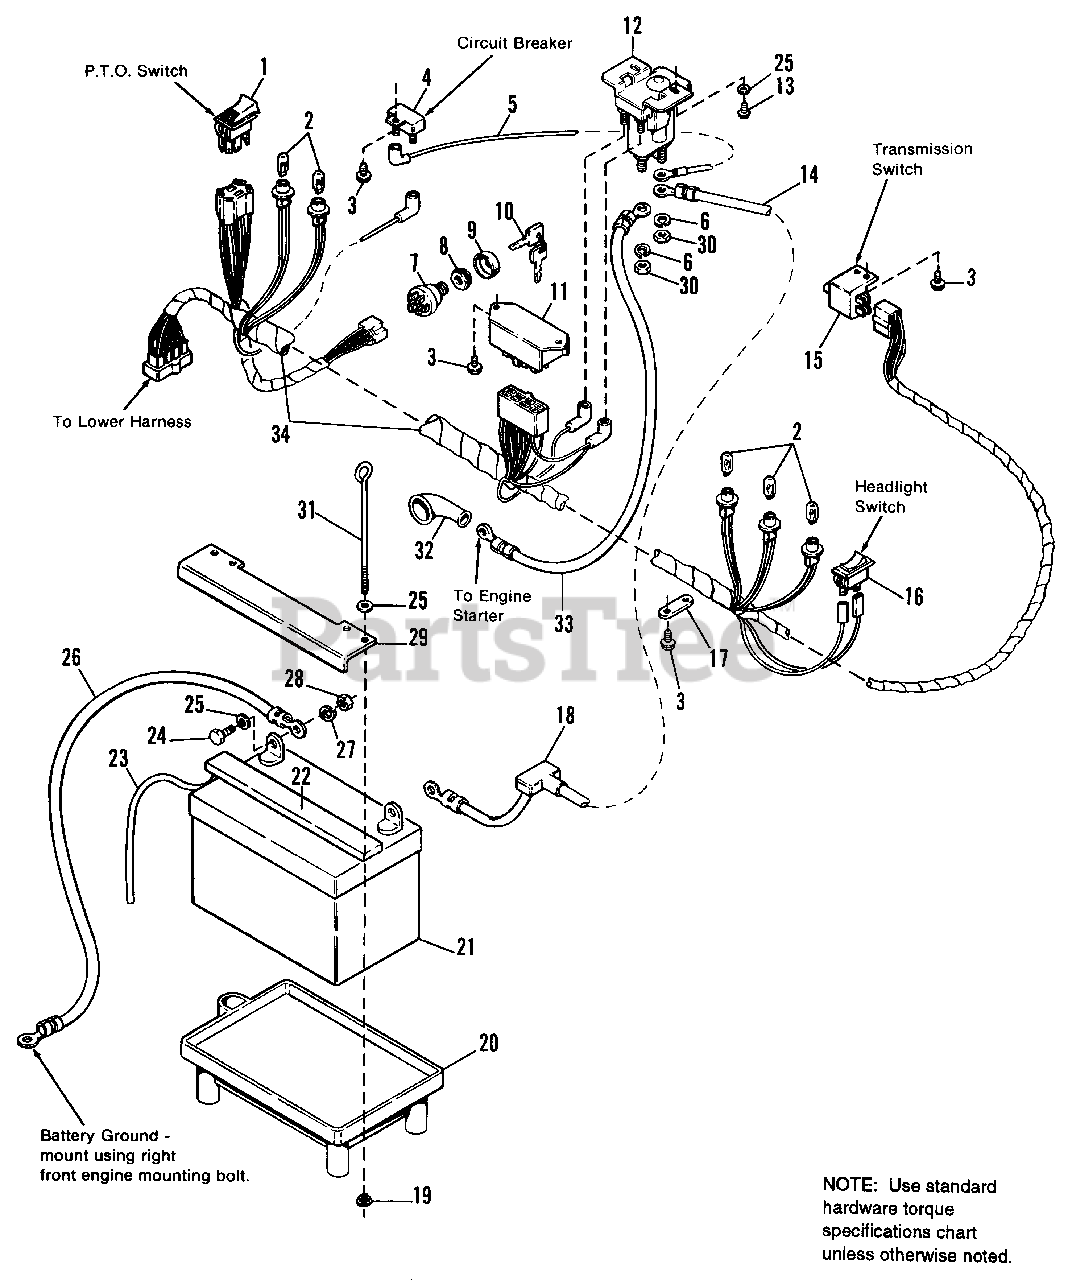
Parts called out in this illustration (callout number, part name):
1	SWITCH, PTO, Electric Clutch
2	BULB, Indicator Light
3	SCREW, Plastite, #8-16 x 1/2
4	CIRCUIT BREAKER
6	LOCKWASHER, 5/16
7	SWITCH, Ignition
8	ADAPTER, Nut
9	COVER, Key Switch
12	SOLENOID
13	SCREW, Plastite, 1/4-20 x 5/8
14	CABLE, Battery to Solenoid
15	SWITCH, Transmission, Neutral Start
16	SWITCH, Headlight
17	STRAP, Wire Retainer
18	BOOT, Insulator
19	NUT, Plastic, 1/4-20
20	TRAY, Battery
21	BATTERY, 39 Amp
22	VENT, Battery
23	HOSE, Battery, Drain
24	CAPSCREW, Hex, 1/4-20 x 3/4
25	WASHER, Plain, 9/32
26	CABLE, Battery to Ground
27	LOCKWASHER, 1/4
28	NUT, Hex, Full, 1/4-20
29	HOLD DOWN, Battery
30	NUT, Hex, 5/16-24
31	ROD, Battery Hold Down
32	COVER, Terminal
33	CABLE, Solenoid to Starter
34	HARNESS, Upper
